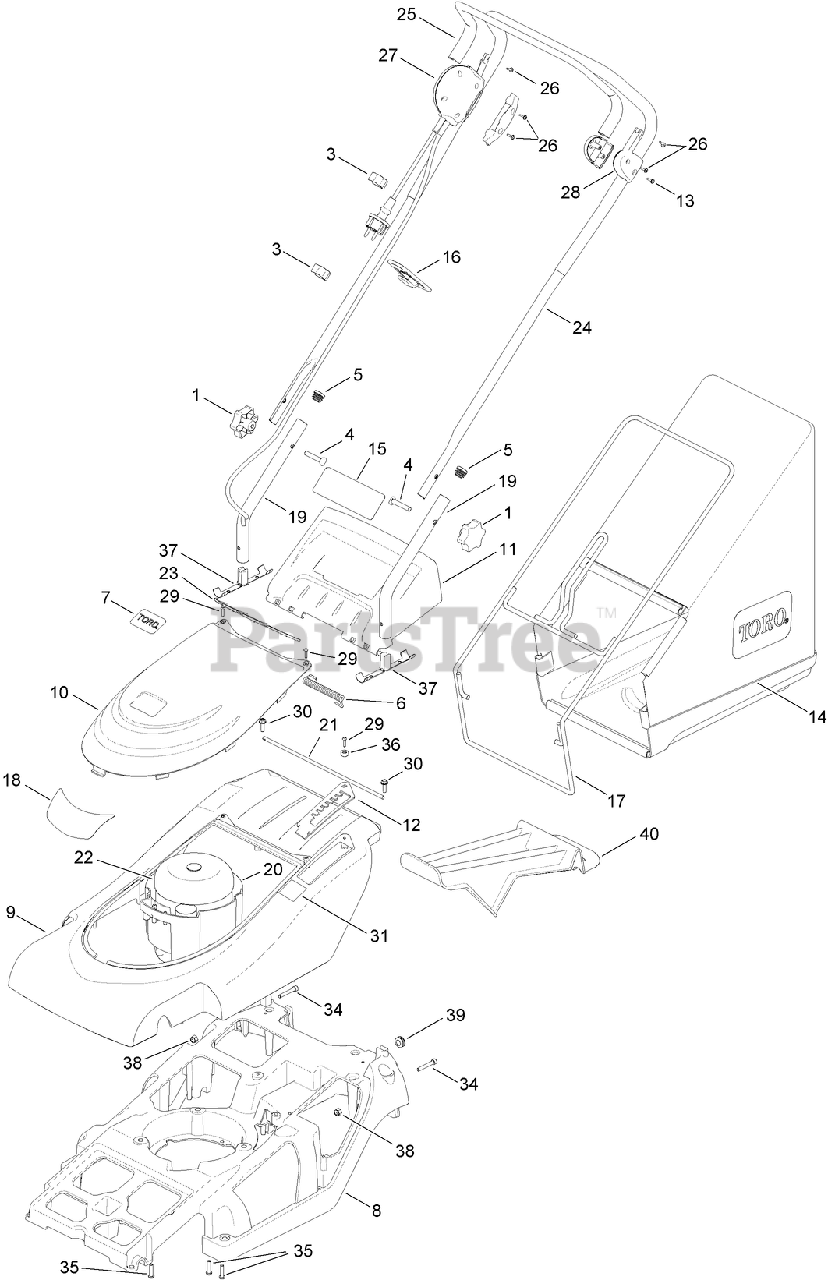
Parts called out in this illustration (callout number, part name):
1	KNOB-HANDLEBAR
3	GUIDE-CABLE
4	BOLT-HANDLEBAR
5	PLUG-TUBE
6	SPRING-DEFLECTOR
7	DECAL-TORO
9	TOP-COVER
10	COVER-MOTOR
11	MOULDING-DEFLECTOR, REAR
12	PLATE-HOC
13	SCREW-PPH
14	GRASSBAG
15	DECAL-SAFETY, ELECTRIC
16	CLEAT-CABLE
20	MOULDING-MOUNT, ELECTRIC MOTOR
21	BAR-HINGE
22	MOTOR-INDUCTION, 1.5KW
23	VENT MESH ASM
24	HANDLEBARS-ELECTRIC
27	SWITCH AND LEAD ASM
28	MOUNT BAIL ARM ASM
30	SCREW-TAPTITE
31	DECAL-HOC
36	CUP-SCREW, ELECTRIC
37	PLUG-HANDLEBAR
38	NUT-NYLOC
39	GROMMET-RUBBER
40	PLUG-MULCHING
